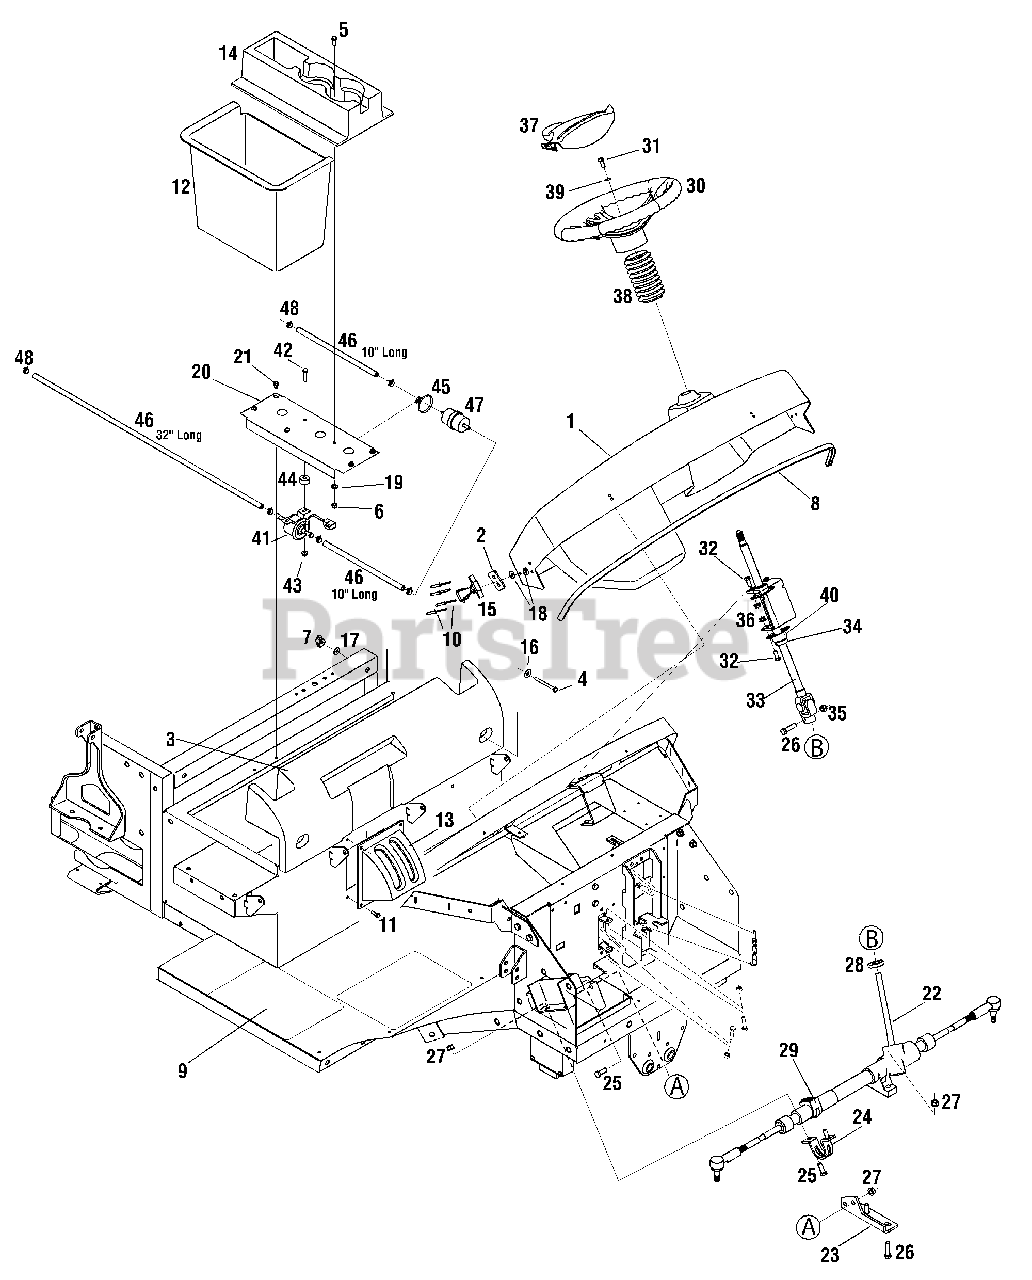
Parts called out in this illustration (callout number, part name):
1	Dash Assembly
2	Hood Mounting Plate
3	Panel, Airbox Cover
4	Hex Screw, 1/4-20 x 2.75
5	Hex Screw, 1/4-20 x .75, Gr5
6	Hex Lock Nut, Nylon, 1/4-20
7	Wing Nut, 1/4-20
8	Trim, Bulb Seal, 1/4
9	Foot Pad, Abrasive
10	Rivet, Pop, .187
11	Rivet, Pop, .188
12	Container, Bulkhead
13	Panel, Shift Cover
14	Console, Cup Holder
15	Handle, Latch
16	Flat Washer, 349 x .875 x .04
17	Washer, Flat, .28 x .74 x .063
18	Washer, Flat, .194 x .62 x .063
19	Washer, Flat, .25 x .630 x .0515
22	Gear Assembly, Steering
25	Hex Screw, 3/8-16, 1.00, Gr5
26	Hex Screw, 3/8-16, 1.50, Gr5
27	Nut, Flange Lock, 3/8-16
28	Grommet, Steering Shaft
29	Bushing, Rubber
30	Wheel, Steering
31	Hex Screw, 5/16-18, .75, Gr5, Patch
32	Hex Screw, 5/16-18, .75, Gr5
33	Shaft, Steering, 5/8 Spline
34	Collar, .75
35	Nut, Hex Lock Nylon, 3/8-16
36	Nut, Flange Lock, 5/16-18
37	Cover, Steering Wheel
38	Bellow, Steering, 4.75 Lg
39	Washer, Flat, .344 x .688 x .065
40	Bearing, Flange, .75 ID, Self-Aligning
41	Pump Assembly, Fuel
42	Hex Screw, 1/4-20 x 1.25
43	Flange Lock Nut, 1/4-20
44	Bushing, .96OD x .50
45	Cable Tie
46	Fuel Line Hose
47	Fuel Filter
48	Clamp, Hose
